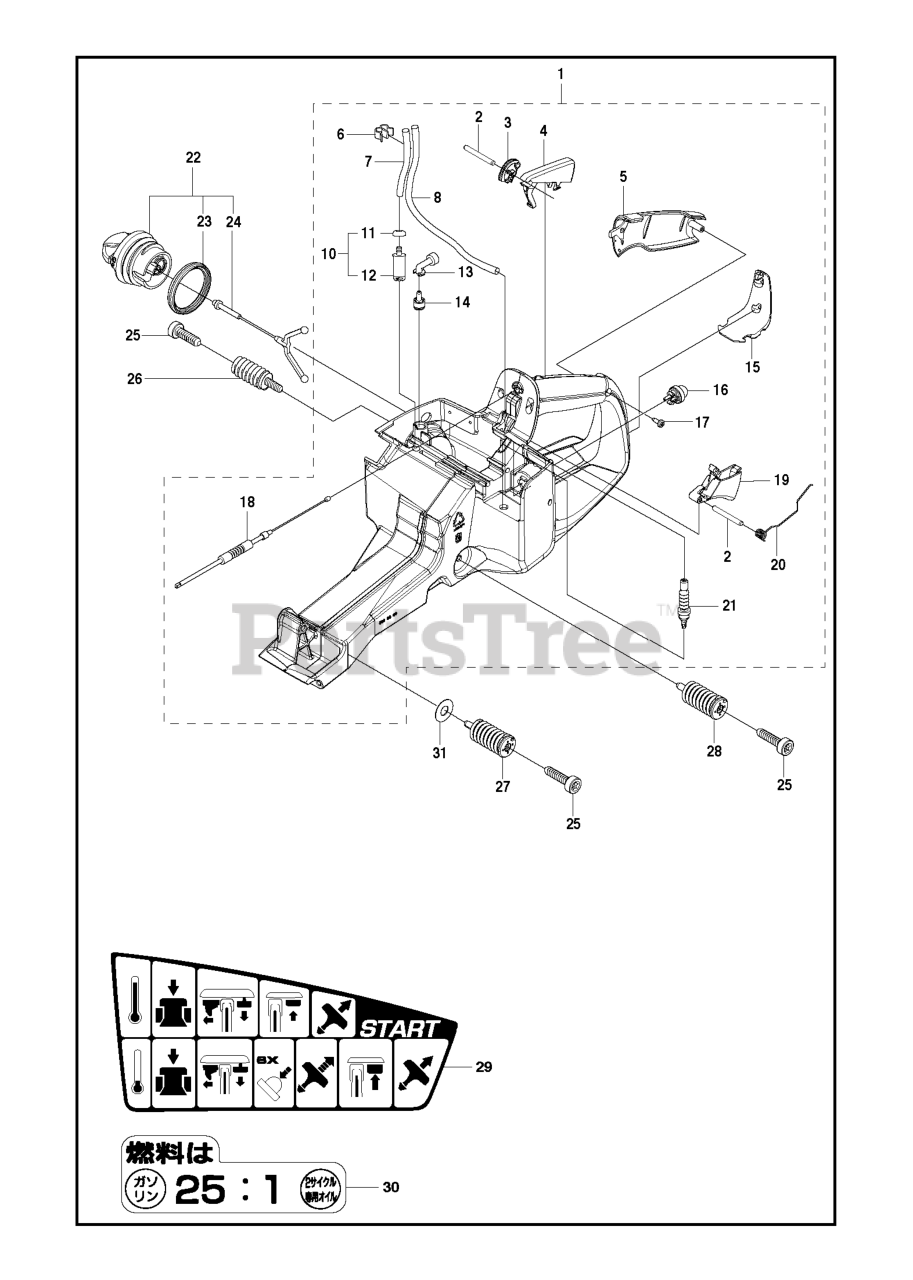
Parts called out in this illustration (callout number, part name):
1	RP FUEL TANK ASSY
2	PIN 3X25
4	THROTTLE LOCKOUT
7	FUEL HOSE SPIRAL 300
8	FUEL HOSE L=183
13	TANK VENT ASSY
14	FUEL TANK VENT
15	GROUND SUPPORT REAR K970
16	AIR CLEANER ZAMA
17	SCREW CITXPANT
18	THROTTLE CABLE ASSY
19	THROTTLE CONTROL
21	FUEL HOSE PURGE RETURN K970
22	TANK CAP ASSY
26	AV ELEMENT
27	ANTIVIBRATION ELEMENT
28	ANTIVIBRATION ELEMENT
29	DECAL START INSTRUCTION K970 I
